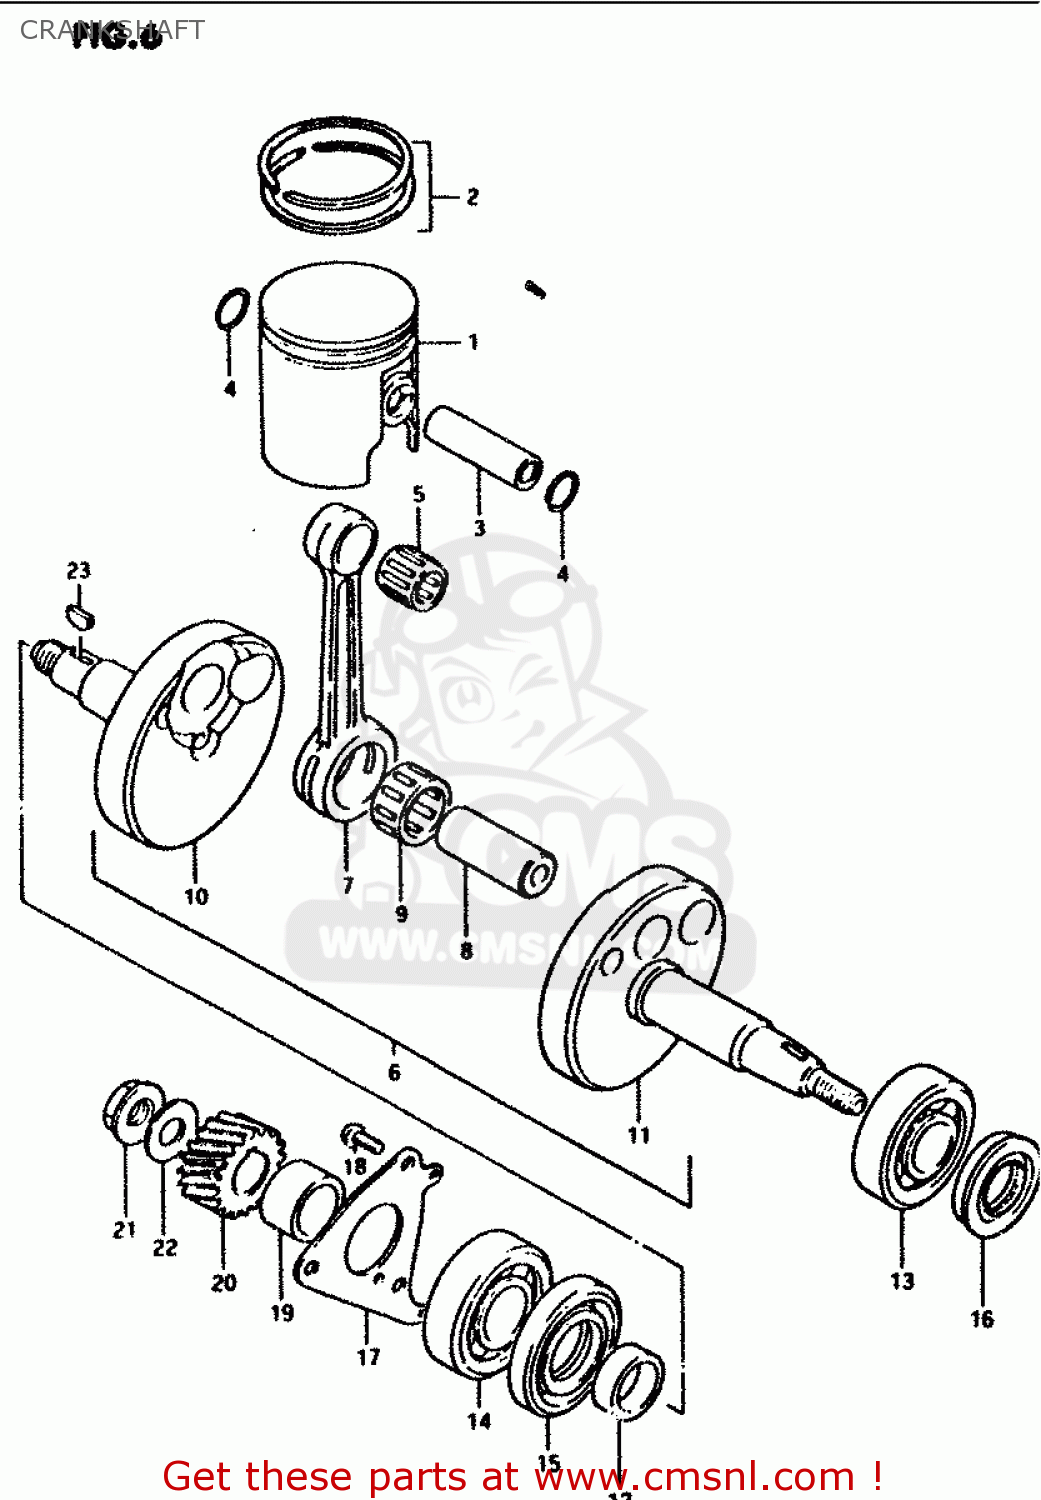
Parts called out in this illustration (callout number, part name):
1	PISTON
2	RING SET,PISTON
3	PIN,PISTON
4	RING,SNAP
5	ROLLER BEARING (12X16X1
6	CRANKSHAFT ASSEMBLY
7	ROD,CONNECTING
8	PIN,CRANK
9	BEARING
10	CRANKSHAFT,RIGHT
11	CRANKSHAFT,LEFT
12	SPACER(20X26X9)
13	BEARING(20X47X14)
14	BEARING(20X47X14)
15	SEAL,OIL(26X47X7.3)
16	SEAL,OIL(19.6X37X8)
17	RETAINER,CRANKSHAFT BEARING,R
18	SCREW
19	SPACER(20X26X14)
20	GEAR,PRIMARY DRIVE NO.19
21	NUT
22	WASHER
23	KEY
